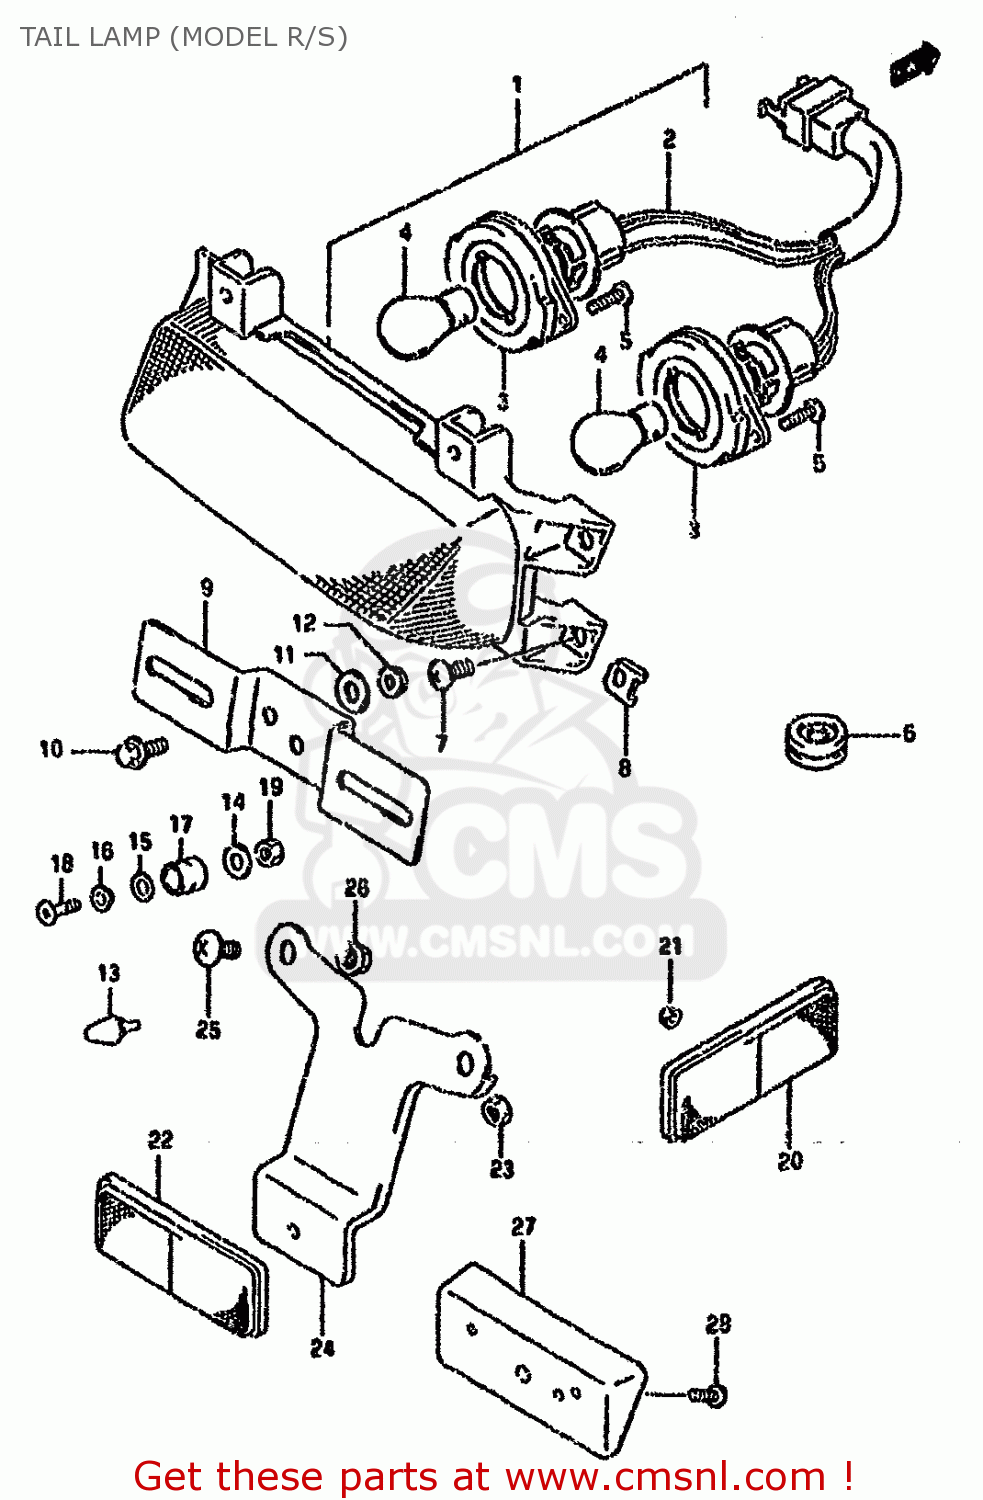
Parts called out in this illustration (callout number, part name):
1	LAMP ASSY, REAR COMBINATION
2	SOCKET & CORD ASSY
3	CUSHION
4	BULB(12V21/5W)
5	SCREW
6	GROMMET
7	SCREW 5X12
8	NUT
9	BRACKET,LICENSE PLATE
10	BOLT
11	WASHER(6.5X20X1.6)
12	NUT
13	CUSHION
14	WASHER
15	WASHER(6.5X16X1.2)
16	WASHER
17	CUSHION, PLATE
18	SCREW
19	NUT
20	REFLEX REFLECTOR,FR SIDE
21	NUT
22	REFLECTOR ASSY,RR
23	NUT
24	BRACKET,RR RR
25	SCREW 6X12
26	NUT
27	SCREW 6X12
28	NUT
29	SPACER,RR RR
30	SCREW
